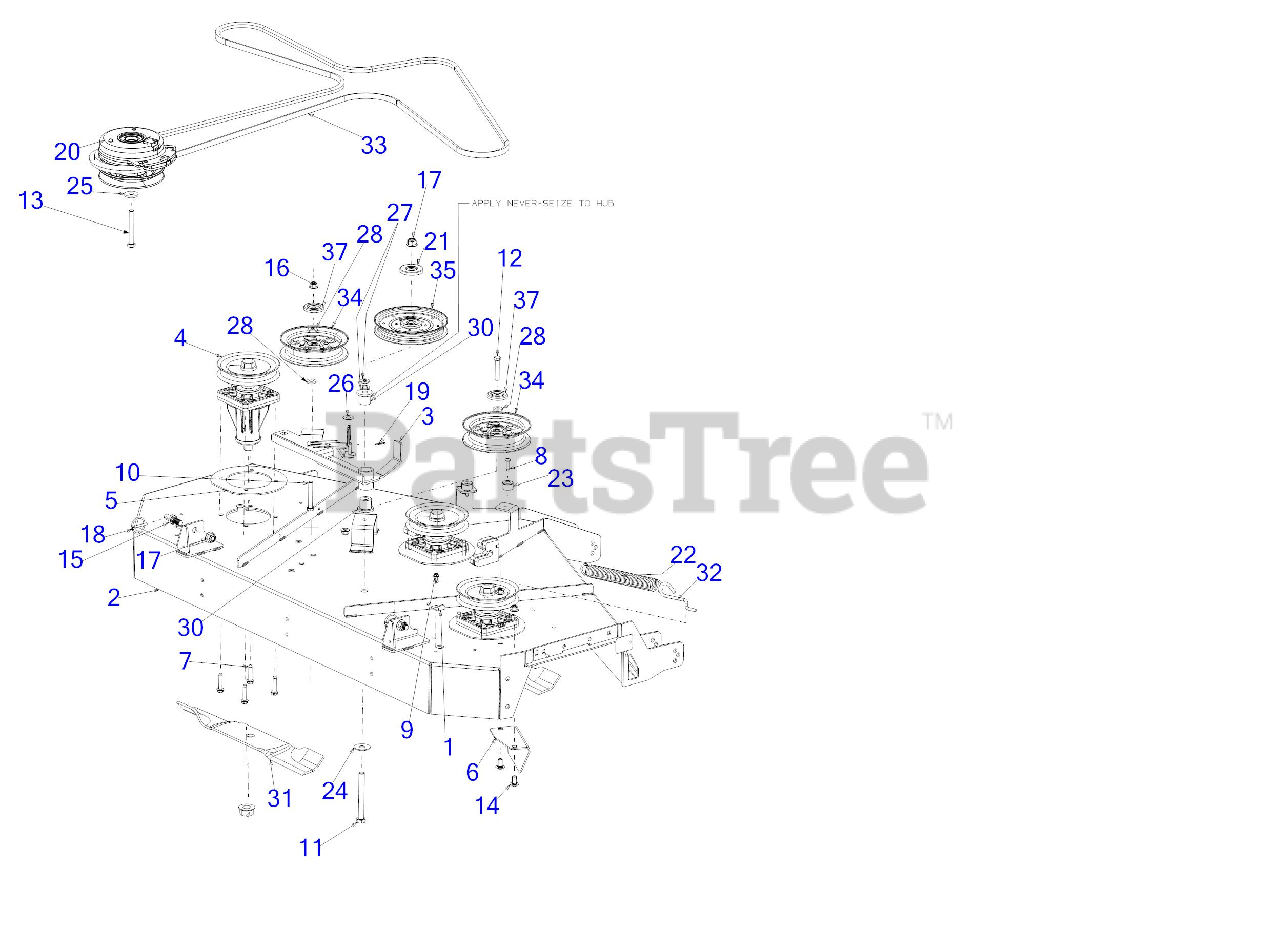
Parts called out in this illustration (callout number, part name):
1	HOOK RETAINER BRACKET
2	54"FAB DECK SHELL
3	IDLER ARM ASSEMBLY
4	BLADE SPINDLE ASSEMBLY (W/PULLEY)
5	SPINDLE REINFORCEMENT PLATE
6	DECK CHUTE BAFFLE
7	SCREW 5/16-18 x 1.50
8	SCREW 1/4-20 x 1.0
9	SCREW 1/4-20 X.500
10	HEX SCREW-3/8-16X2.5 GR5
11	SCREW 1/2-13 x 4.5 GR 5
12	SCREW 3/8-16 x 2.0 GR5
13	SCREW 7/16-20 x 3.25 GR5
14	CARRIAGE BOLT 3/8-16 x .75
19	COTTER PIN 3/32
20	ELECTRIC PTO CLUTCH
21	PULLEY CAP 1/2"
22	EXTENSION SPRING
24	WASHER .51 x 1.5 x .07
25	FLAT WASHER .445 x 1.248 x .170
26	FLAT WASHER
27	FLAT WASHER
28	FLAT WASHER
30	SHOULDER SPACER
31	19" BLADE (HI LIFT)
32	DECK SPRING HOOK
33	V-BELT B SEC x 154
34	IDLER PULLEY 5.0" DIA
35	IDLER PULLEY 6.0" DIA
37	IDLER PULLEY CAP
